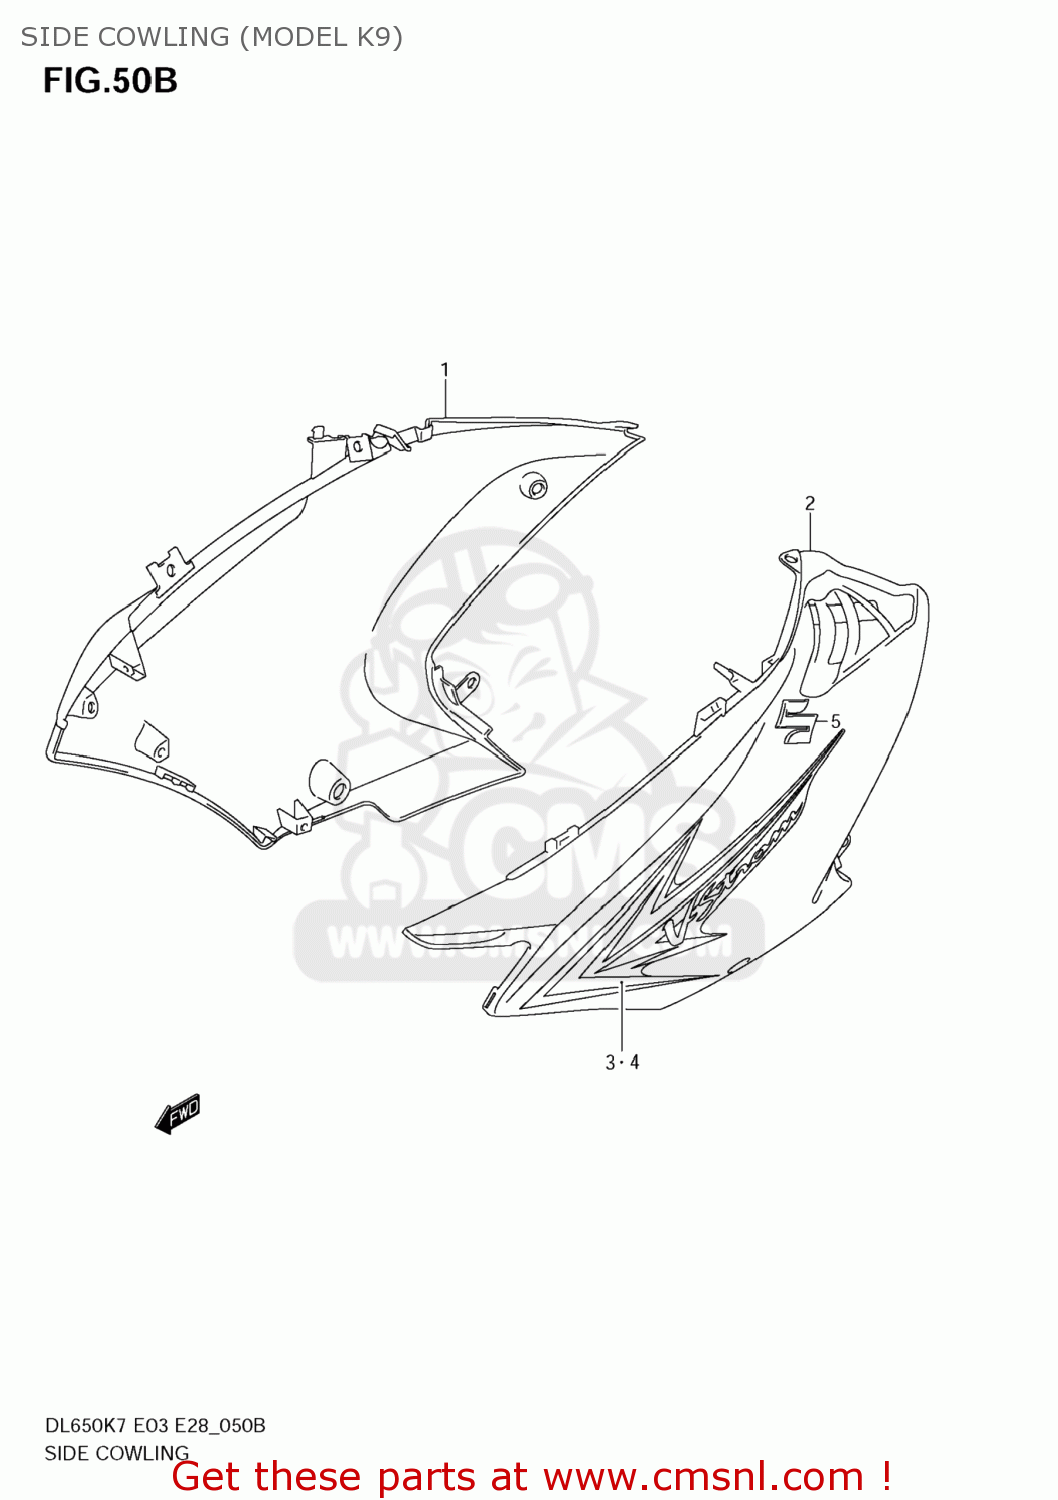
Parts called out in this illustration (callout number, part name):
1	COWLING ASSY,SIDE,R
2	COWLING ASSY,SIDE,L
3	TAPE,COWL SIDE,R
4	TAPE,COWL SIDE,L
5	EMBLEM,S
